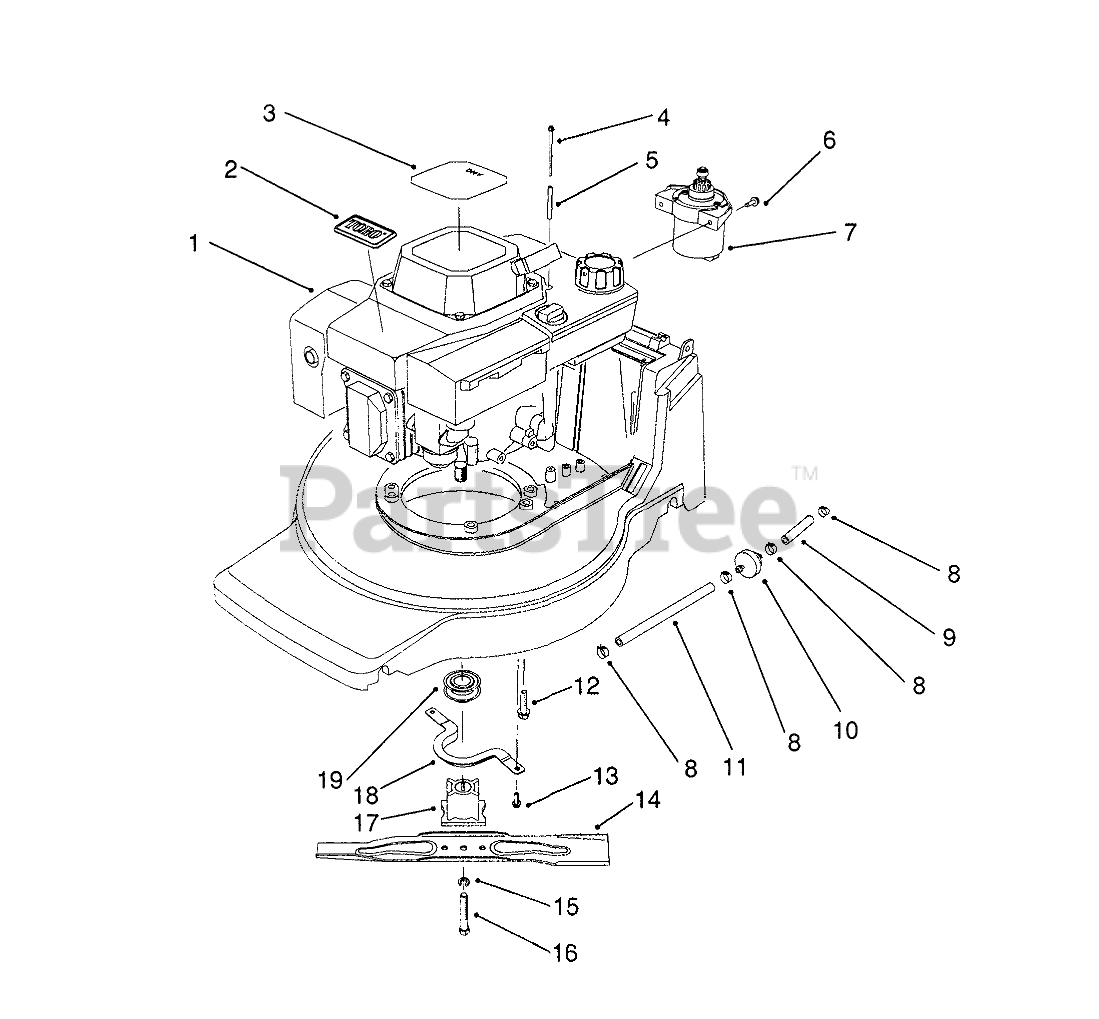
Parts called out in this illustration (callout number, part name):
1	ENGINE ASSY OHV BBC/K
2	TORO LOGO PLT
3	DECAL-HV INT'L
4	THRD FORMING SCREW
5	TUBULAR SPACER
6	SCREW
7	STARTER MOTOR ASM
8	CLAMP-FUEL LINE
9	LINE-GAS
10	FILTER-FUEL
11	HOSE-FUEL
12	SCREW-HWHTF
13	SCREW-HWH
14	Blade-48cm
15	WASHER-LOCK
16	BOLT-BLADE
17	BLADE RETAINER - 25 MM
18	Guide-Belt
19	PULLEY-DRIVE, ZONE START
